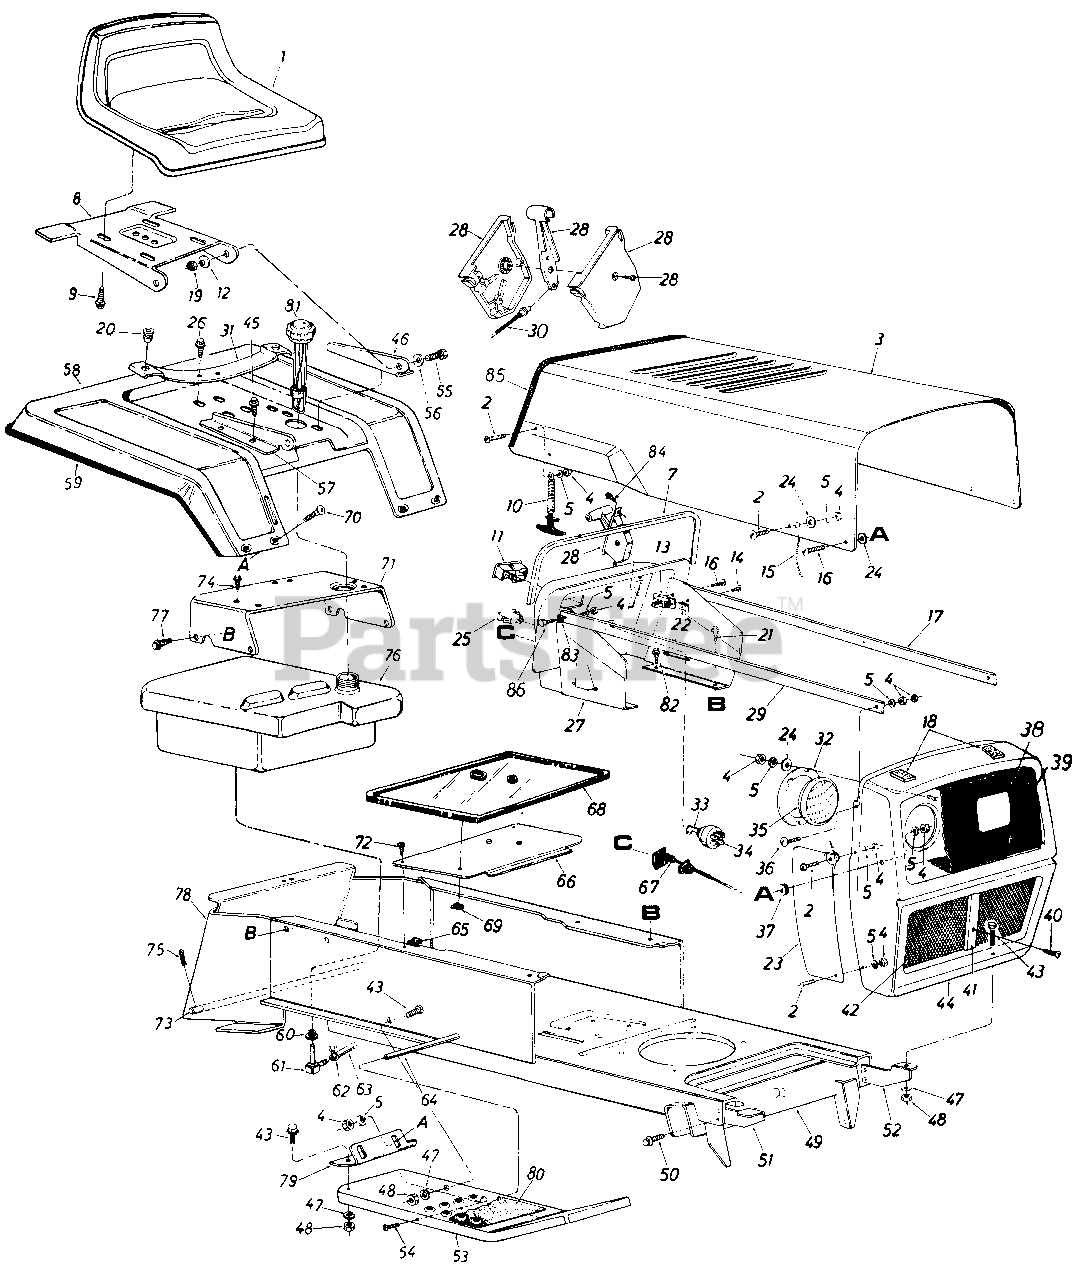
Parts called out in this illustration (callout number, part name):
1	Seat Assembly
2	Truss Mach. Scr. 1/4-20 x .50" Lg.
5	L-Wash. 1/4" Scr.*
7	Vinyl Molding Strip-29"
8	Seat Pivot Bracket
9	Hex Wash. AD AB-Tap Scr. 318 x .75" Lg.
10	Hood Latch Ass'y.
11	Ammeter
12	Bell-Wash 341 I.D. x .88" O . D
13	Circuit Breaker 8 Amp.
14	Hex Tap Scr. #10 x .50" Lg.*
15	Hood Stop
16	Truss Mach. Scr. 1/4-20 x .75" Lg.*
17	Grille Positioning Rod
18	PVC Foam Strip 1/2 x 1.00" x 2.00" Lg.
19	Hex Cent. L-Nut 5/16-18 Thd.
20	Grommet
21	Hex Thd. Rolling Scr. 1/4" x .50" Lg
22	Speed Nut #10Z
23	Grille Side Panel-R.H.
24	Fl-Wash. 1/4" I.D.
25	Light Switch
26	Hex Wash. Hd. Self-Tap Scr. 5/16-18 x .50" Lg.
27	Dash Panel Ass'y.
28	Throttle Control Box Comp.
29	Grille Positioning Rod
30	Throttle Control Wire
31	Seat Spring
32	Head Lamp Retainer
33	Ignition Key
34	Ignition Switch
35	Head Lamp
36	Truss Machine Scr. 1/4-20 x .75" Lg.
37	Rubber Wash. .50" I.D. x 1.00 O.D. x .25 Thk.
38	Headlight Bezel
39	Hex Wash. Hd. Scr. #8-32 x .38" Lg.
40	Truss Mach. Scr. #10-24 x .62" Lg.
41	Center Moulding
42	Grille Screen
43	Hex Scr. 5/16-18 x .75" Lg.
44	Grille Ass'y
45	Hex Wash. Hd. Self-Tap Scr. 5/16-18 x .50" Lg.
46	Seat Brkt.-L.H.
47	L-Wash. 5/16" Scr.
48	Hex Nut 5/16-18 Thd.
49	Lower Frame Ass'y.
50	Hex Thd. Rolling AB Scr. 5/16 x .75" Lg.
51	Grille Mount Brkt.-R.H.
52	Grille Mount Brkt.-L.H.
53	Running Board-R.H.
54	Truss Mach. Scr. 5/16-18 x .75" Lg.
55	Hex Bolt 5/16-18 x .75" Lg.
56	Bell-Wash. .34" I.D. x .88" O.D.
57	Seat Brkt.-R.H.
60	Bushing
61	90ø Nipple
62	Hose Clamp
63	Gas Line 46" Lg.
64	Running Board Rod
65	Speed Nut
66	Transmission Cover
67	Choke Control Comp.
68	Transmission Cover
69	Speed Nut 1/4" Stud
70	Carriage Bolt 1/4-20 x .50" Lg.*
71	Seat Mounting Channel
72	B-Tap Scr. #10 x .50" Lg.
73	Hitch Rod
74	Hex Wash. Hd. Self-Tap Scr. 5/16-18 x .50" Lg.
75	Internal Cotter Pin
76	Gas Tank
77	Hex Wash. Hd. AB-Tap Scr. 318 x .75" Lg.
78	Hitch Plate
81	Gas Gauge
82	Hex Thd. Rolling Scr. 5/16-24 x .75" Lg.
83	External Wash. 1/4" I.D.
84	Truss. Mach. Scr. #10 x .5" Lg.
85	Trim strip-30" Lg.
86	Truss Mach. Scr. 1/4-20 x 1.00
